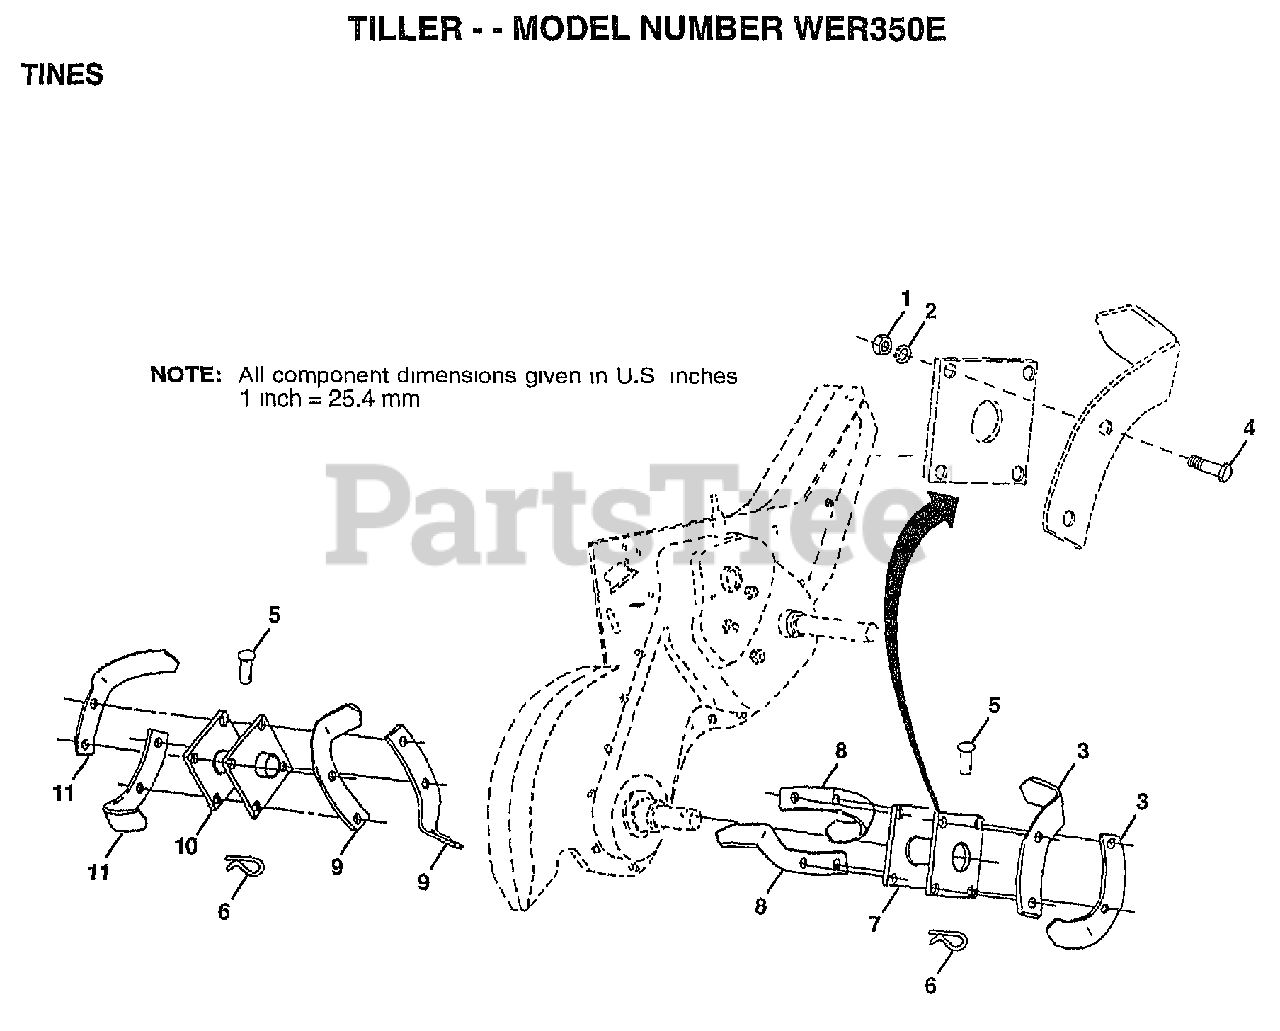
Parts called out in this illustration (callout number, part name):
2	LOCKWASHER
4	BOLT
5	PIN.CLEVIS.SHEAR
6	RETAINER.SPRING
7	ASM HUB&PLATE RH
8	"TINE.RH.12"""
9	"TINE.LH.12"""
10	ASM HUB&PLATE LH
